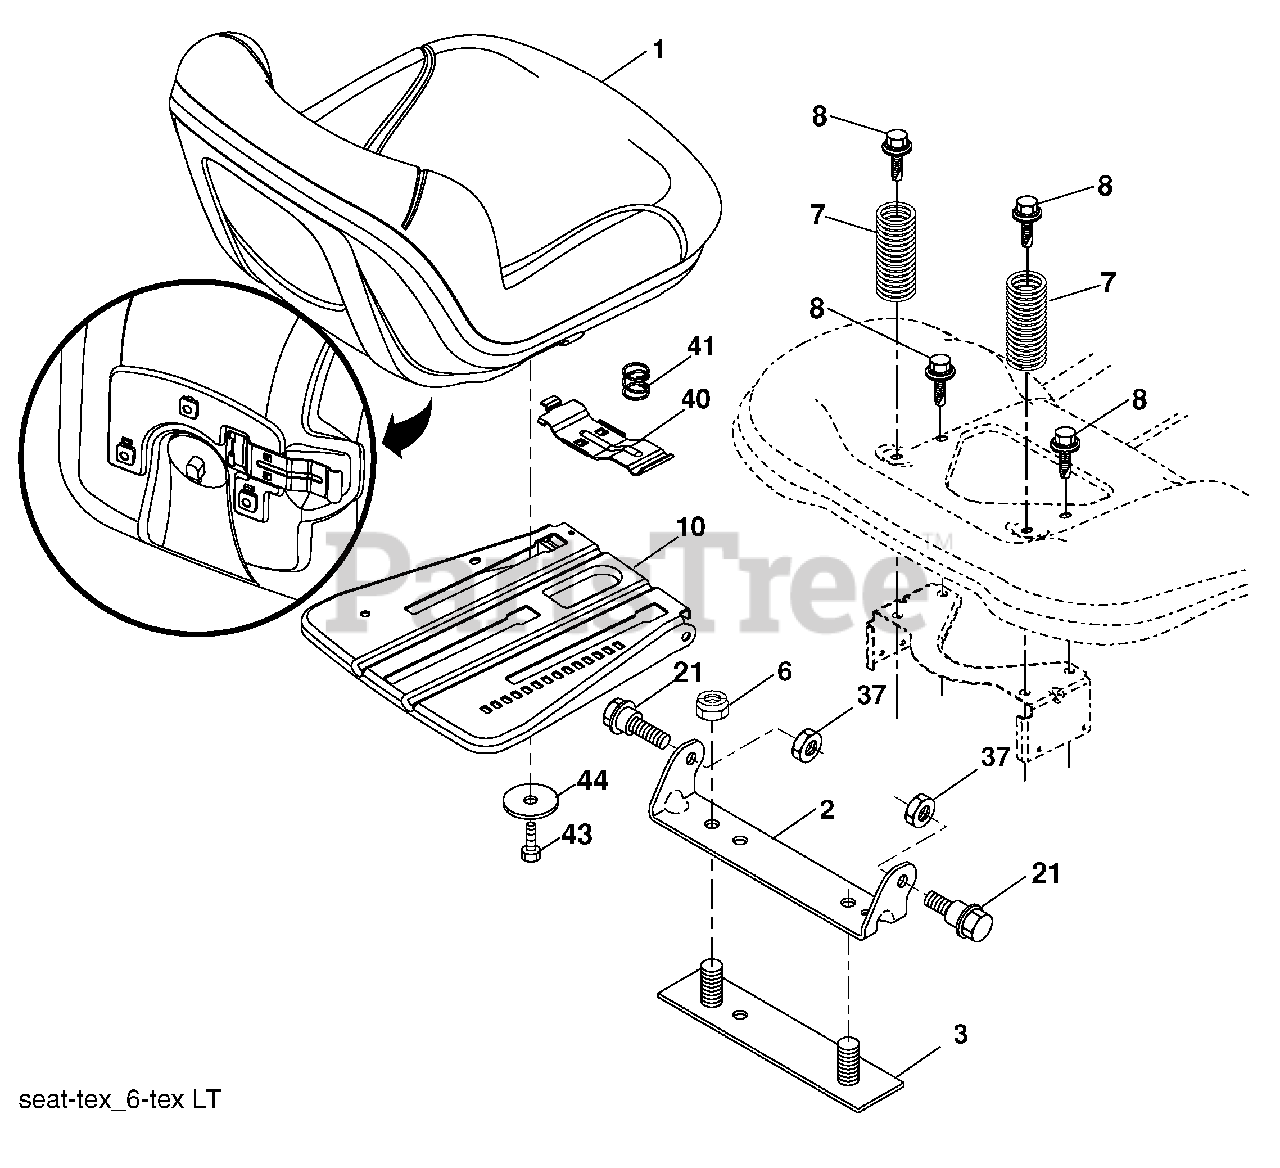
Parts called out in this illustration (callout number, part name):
1	Seat
2	Bracket Pivot Fender
3	Strap, Asm Fender
6	Nut, Lock w/Ins. 3/8-16 unc
7	Spring, Seat Cprsn
8	Bolt 5/16-18 unc x 3/4 w/Sems
10	Pan, Seat
21	Bolt, Shoulder 5/16-18
37	Nut, Lock 5/16-18 unc
40	Handle Slide Seat
41	Spring Latch Seat
43	Bolt Fin Hex 3/8-16 unc x 3/4
44	Washer 13/32 x 2-3/8 x 12 Ga.
